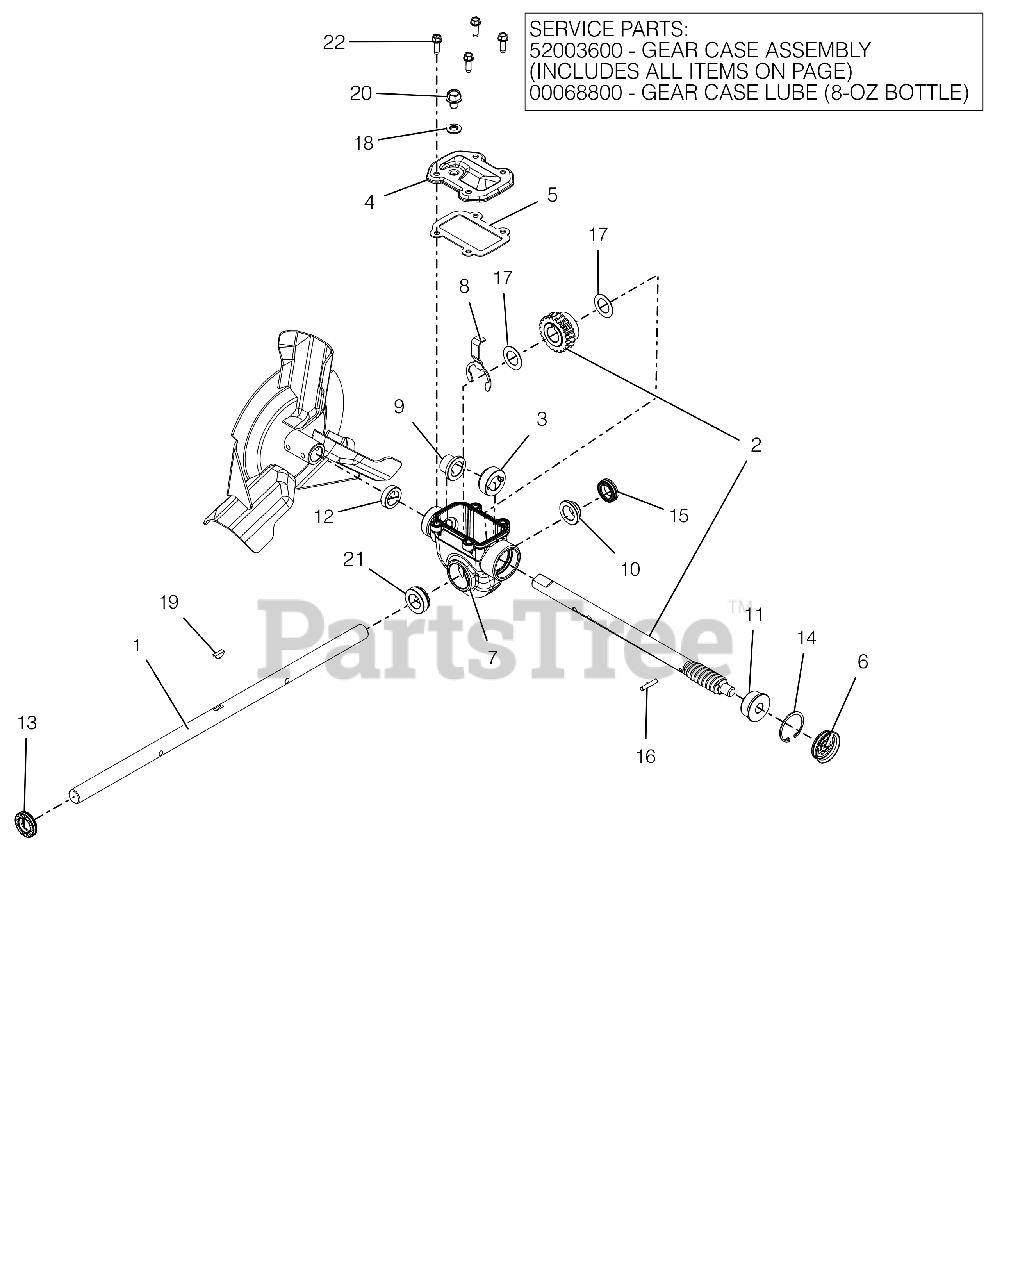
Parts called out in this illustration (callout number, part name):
1	SHAFT, RAKE - 20" (.750 DIA)
2	SHAFT AND WORM GEAR ASSEMBLY
3	THRUST COLLAR, .75" ID SLIPFIT
4	COVER, TOP - COMPACT
5	GASKET, TOP - COMPACT GEARCASE
6	COVER, GEAR CASE 1.50"
7	GEARCASE, COMPACT ALUMINUM
8	BUSHING RETAINER, COMPACT
9	BSHG-FLG .755X.878X.75X1.25
10	BSHG-FLG .755X.878X.424X1.25
11	BSHG-FLG .503X1.303X.62X1.465
12	SEAL-OIL .748X1.125X.312 TB2-H
13	SEAL-OIL .748X1.300X.250 TBC29
14	RG-RTNG-INT 1.500X.050
15	SEAL-OIL .748X1.125X.312 TBC29
16	PIN-STR .188X1.00 6150
17	WSHR-FL-STL .760X1.225X.032 YZ
18	WSHR-BND-SEAL .38X.75X.11 GALV
19	KEY-WDRF .19X.63 HRD #61
20	@SCR-ROLOK .38-16X.50 HWH YWZC
21	BSHG-FLG COMPACT, RIGHT
22	SCR-TAP-PM .25-20X.75 TR YWZ
23	GEAR CASE, 24" ALUM SM TOP-LD
24	ARIENS L3 LUBE, 8 OZ BOTTLE
